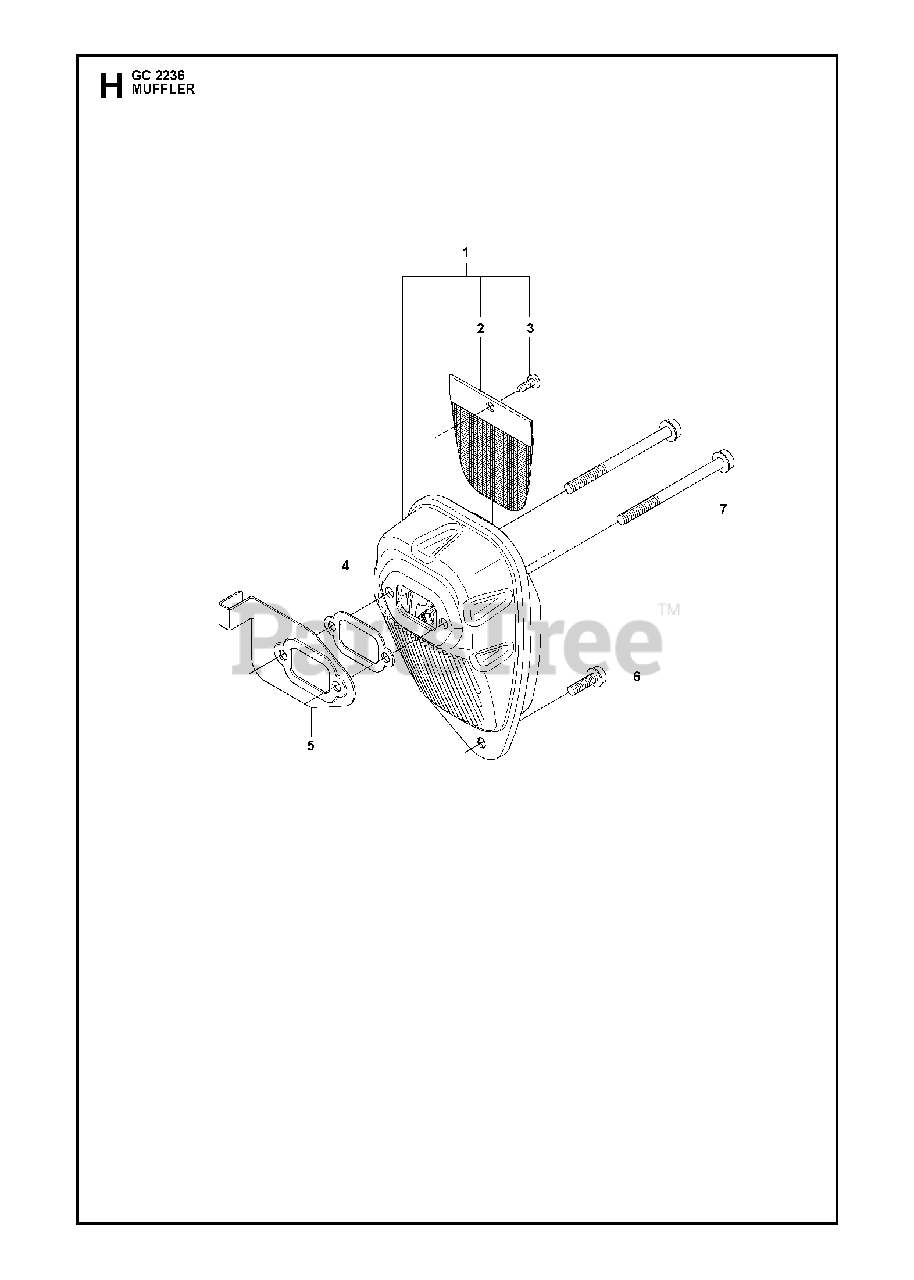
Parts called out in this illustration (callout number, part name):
1	MUFFLER KIT COMPLETE
2	SPARK ARRESTER
3	SCREW
4	GASKET MUFFLER
